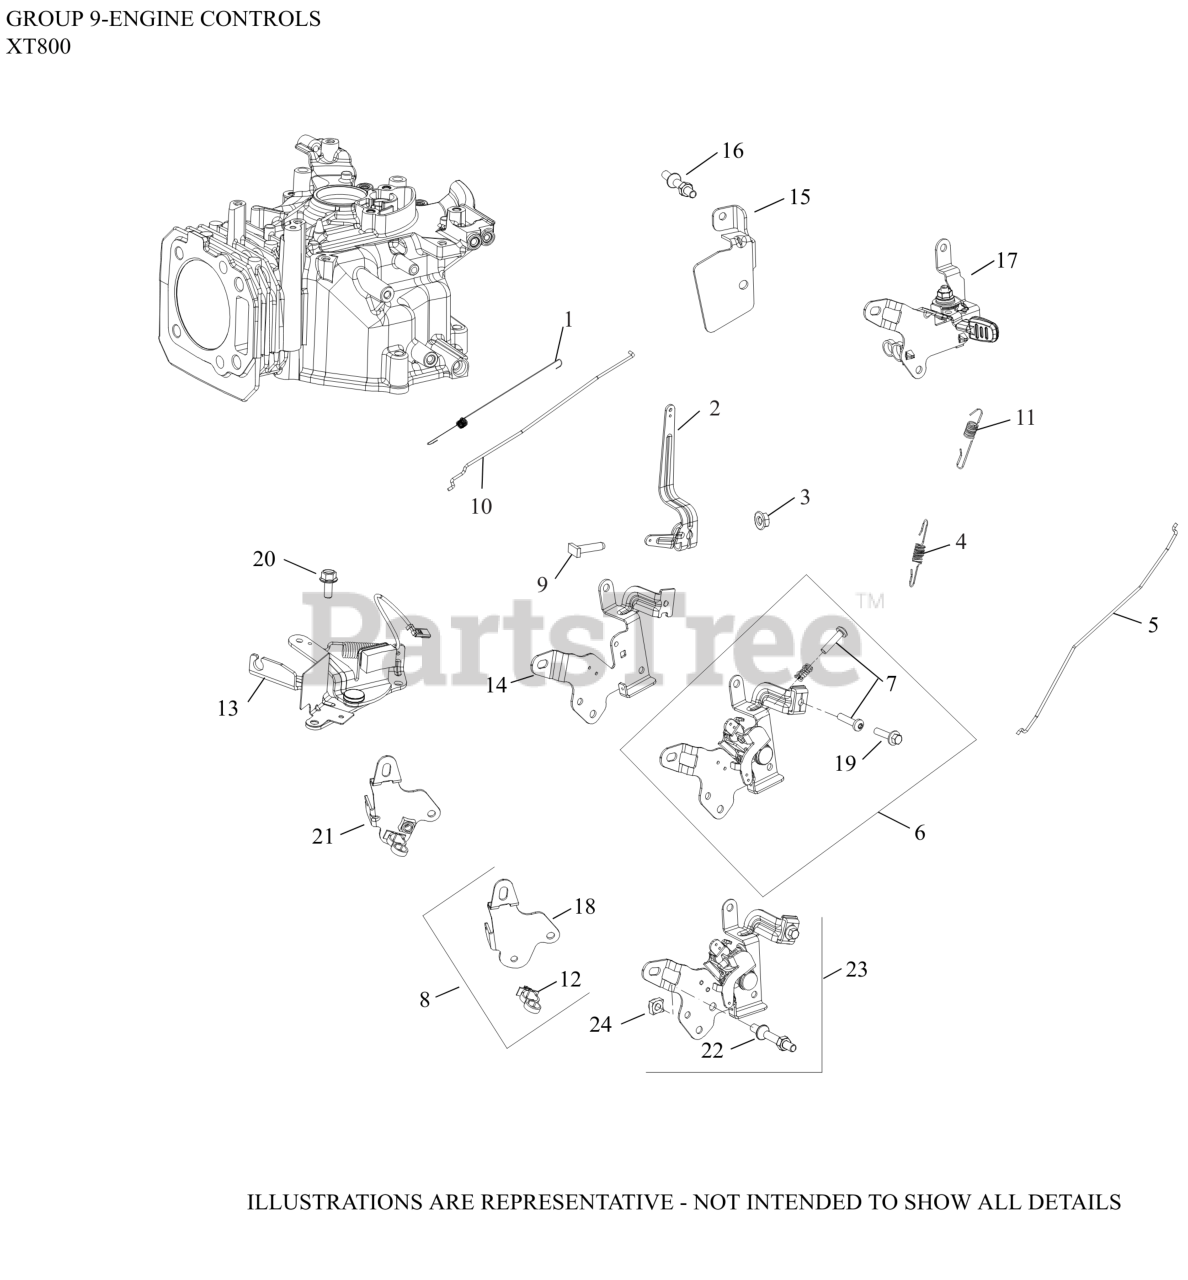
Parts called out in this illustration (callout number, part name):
1	SPRING, LINKAGE
2	LEVER, GOVERNOR-USE 14 090 37-S
4	SPRING, GOV (2800-3300 RPM)
5	LINKAGE, CHOKE
8	BRACKET ASSY-USE 14 126 81-S
9	SCREW, RECTANGLE HEAD (M6)
10	LINKAGE, GOVERNOR - USE 14 079 30-S
